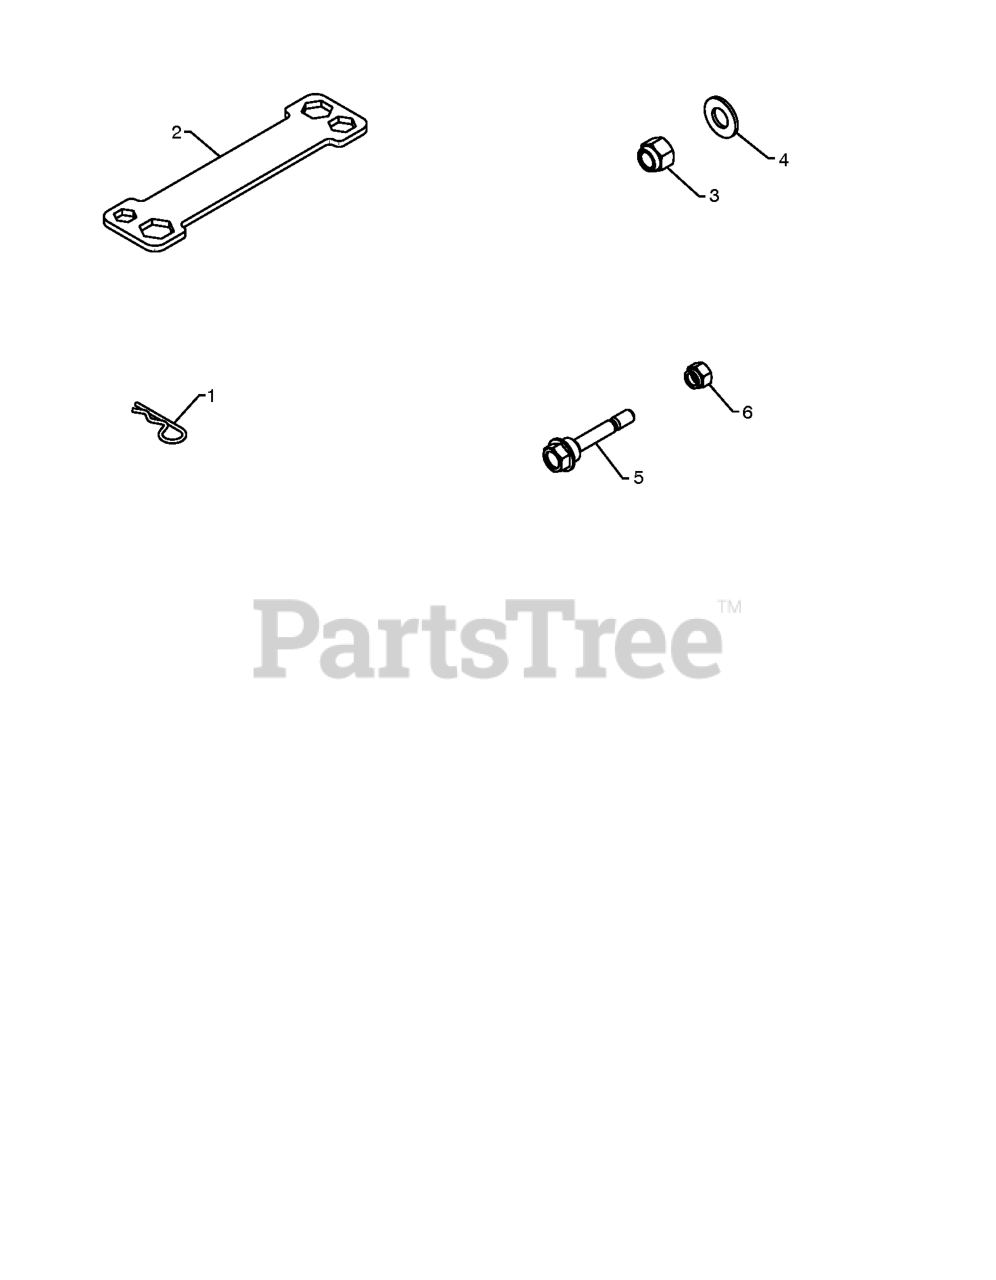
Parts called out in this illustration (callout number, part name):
1	SPRING RETAINER
2	WRENCH.SNOWTHROWER.ZINC.YZ
3	NUT
4	WASHER
5	BOLT.SHOULDER.SHEAR.1/4-20.
6	LOCKNUT.NYLOC.1/4-20
